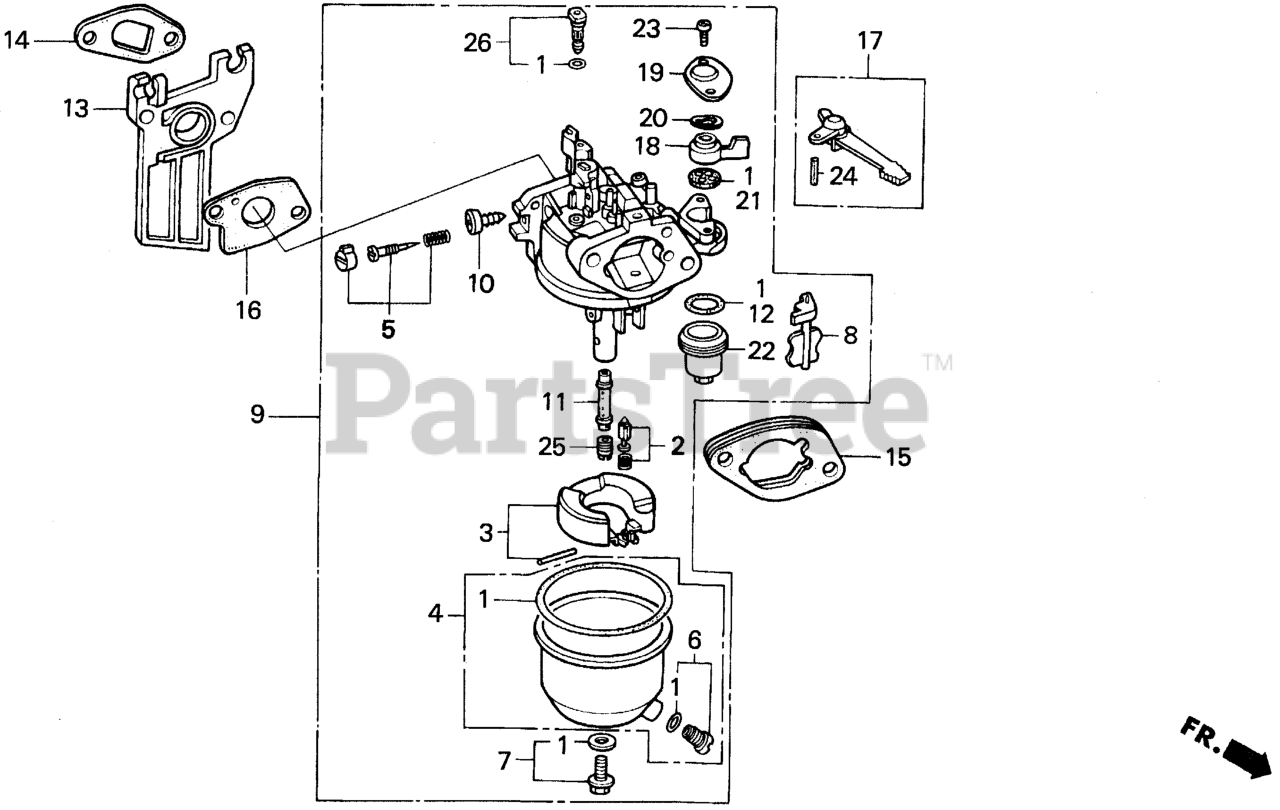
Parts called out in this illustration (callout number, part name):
1	GASKET SET
2	VALVE SET, FLOAT (CARBURETOR NO.) (SEAT NOT INCLUDED)
3	FLOAT SET
4	CHAMBER SET, FLOAT (CARBURETOR NO.) (FOR BE12A A)
4	CHAMBER SET, FLOAT (CARBURETOR NO.)
5	SCREW SET (Honda Code 4219879). (CARBURETOR NO.)
6	SCREW SET, DRAIN (Honda Code 1672187). (CARBURETOR NO.)
7	SCREW SET B
7	SCREW SET
8	CHOKE SET
9	CARBURETOR ASSY. (BE60B B)
10	SCREW, THROTTLE STOP
11	NOZZLE, MAIN
12	GASKET, FUEL STRAINER CUP
13	INSULATOR, CARBURETOR
14	GASKET, INSULATOR
15	SPACER, CARBURETOR
16	GASKET, CARBURETOR
17	LEVER, CHOKE (STD)
18	LEVER, VALVE
19	PLATE, LEVER SETTING (CARBURETOR NO.)
20	SPRING, PETCOCK LEVER (CARBURETOR NO.)
21	GASKET, VALVE
22	CUP, FUEL STRAINER
23	SCREW, PAN (3X8) (CARBURETOR NO.)
24	PIN, SPRING (2X12)
25	JET, MAIN (#55) (CARBURETOR NO.) Use from Engine SN BE03A H to BE03A H.
25	JET, MAIN (#60) (CARBURETOR NO.)
25	JET, MAIN (#58) Use from Engine SN BE30B E.
26	JET SET, PILOT (#35)
